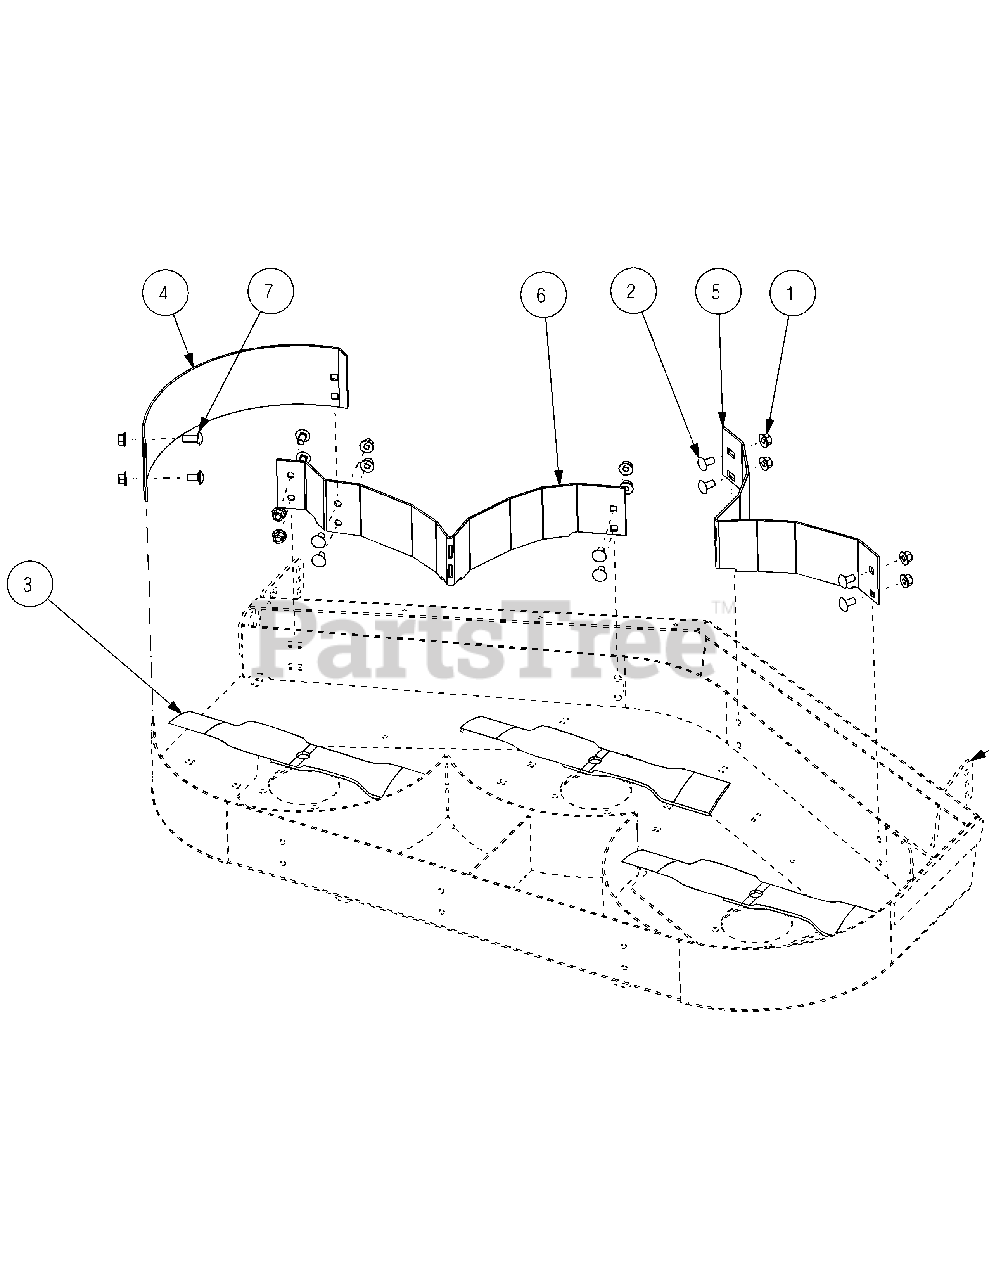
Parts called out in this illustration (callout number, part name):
1	Nut, Flange 3/8-16 GR-5 YZ
2	Bolt 3/8-16X.75 GR5 YZ
3	Blade 17.0 Mulch
4	Baffle Mulch CHUT 48
5	Baffle Mulch TRIM 48
6	Baffle Mulch CNTR 48
7	Bolt 3/8-16 GR5 1.0
